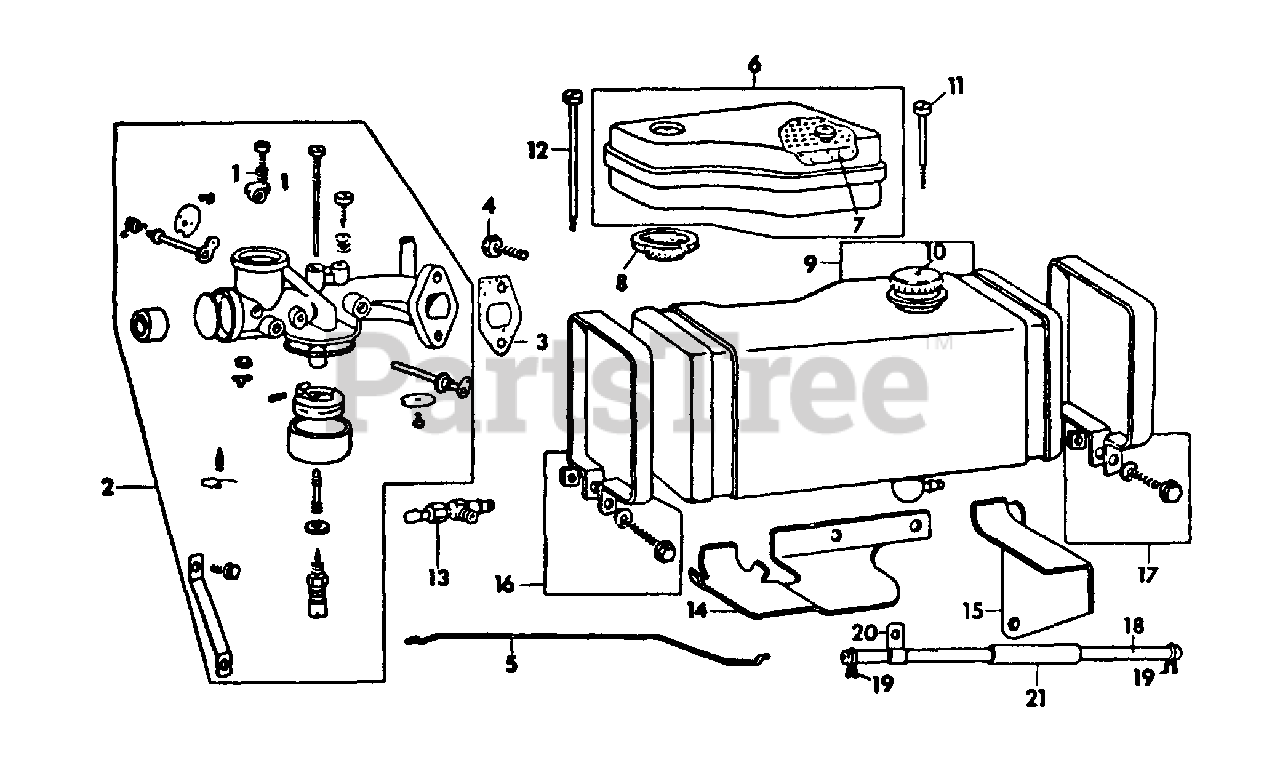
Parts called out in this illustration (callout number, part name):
1	SPRING, THROTTLE ADJUSTING
2	CARBURETOR ASSY
3	GASKET, CARBURETOR
4	SCREW, CARBURETOR MOUNTING
6	CLEANER ASSY, AIR
7	ELEMENT
8	GASKET, AIR CLEANER
9	TANK W/CAP, FUEL
10	CAP, FUEL TANK FILLER
11	SCREW, AIR CLEANER
12	SCREW, AIR CLEANER
13	CONNECTOR & FUEL SHUT-OFF
14	BRACKET, FUEL TANK FRONT
15	BRACKET, FUEL TANK REAR
16	STRAP, FUEL TANK FRONT
17	STRAP, FUEL TANK REAR
18	HOSE, FUEL LINE
19	CLAMP, FUEL LINE HOSE
20	CLAMP, FUEL LINE HOSE
21	BUSHING, HEAT DEFLECTOR
